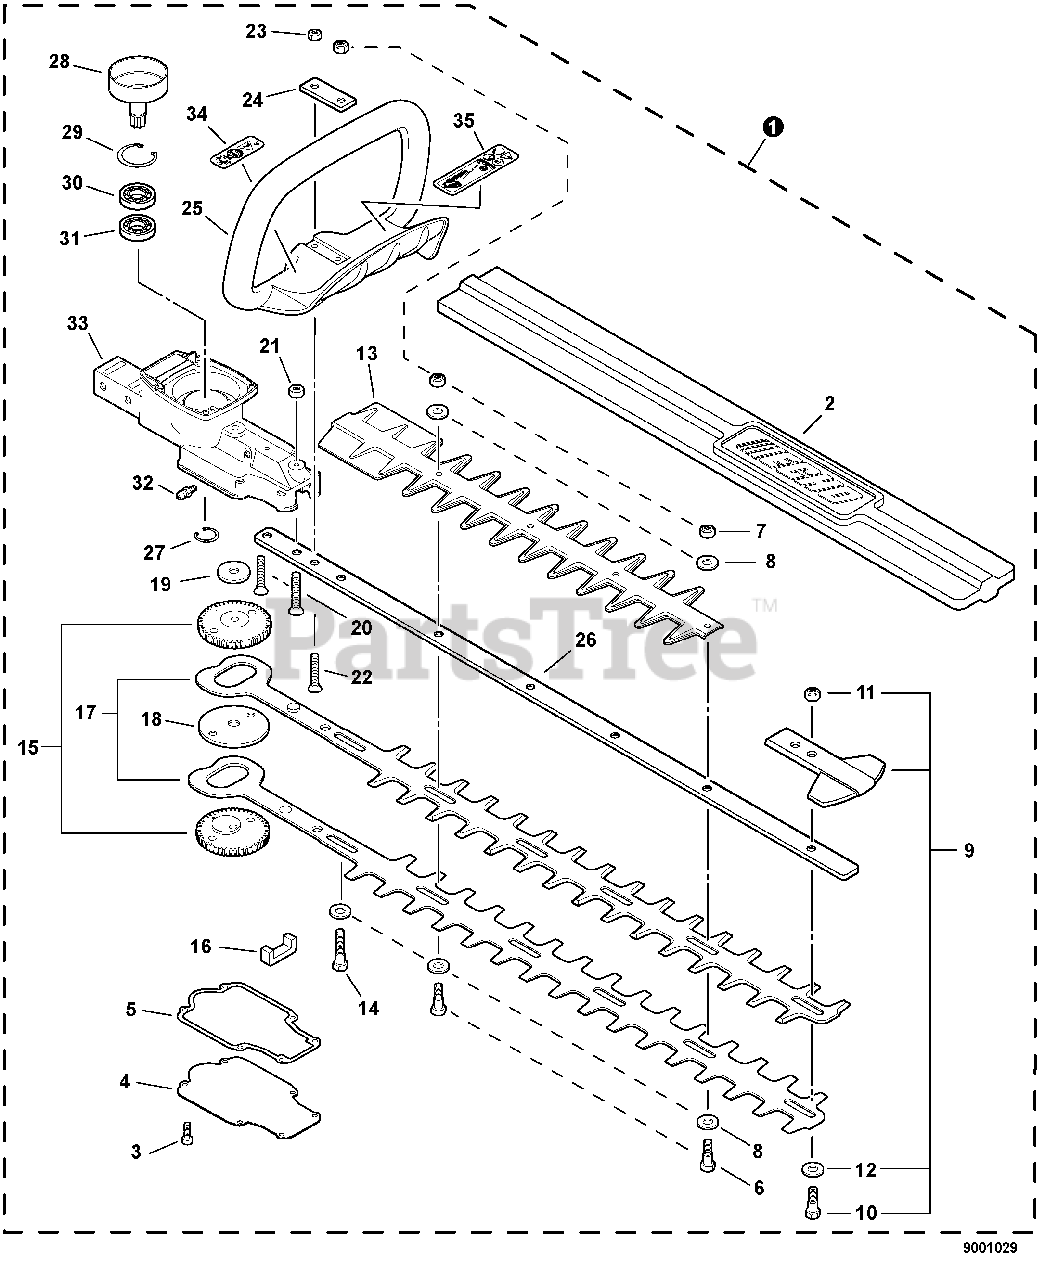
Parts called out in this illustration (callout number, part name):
1	RePower GEAR CASE/BLADES ASSY
2	COVER, BLADE - 20" (50cm)
3	SCREW - 4X12
4	LID, GEAR CASE
5	GASKET, GEAR CASE
6	BOLT - 6X18
7	LOCKNUT - 6
8	WASHER - 6
9	TIP GUARD KIT
10	BOLT - 6X20
11	LOCKNUT - 6
12	WASHER - 6
13	SHIELD, BLADE
14	BOLT - 6X35
15	GEAR - SPUR
16	SEAL, FELT
17	BLADE, TRIMMER
20	SCREW - 6X30
21	LOCKNUT - 6
22	SCREW - 5X30
23	LOCKNUT - 5
25	HANDLE - FRONT
26	SUPPORT, BLADE
27	RING, RETAINING - 14
28	DRUM, CLUTCH
29	RING, RETAINING - 35
30	BEARING, BALL - 6202
31	BEARING, BALL - 6202
32	FITTING, GREASE
33	CASE, GEAR
34	LABEL - CAUTION
35	LABEL - CAUTION
